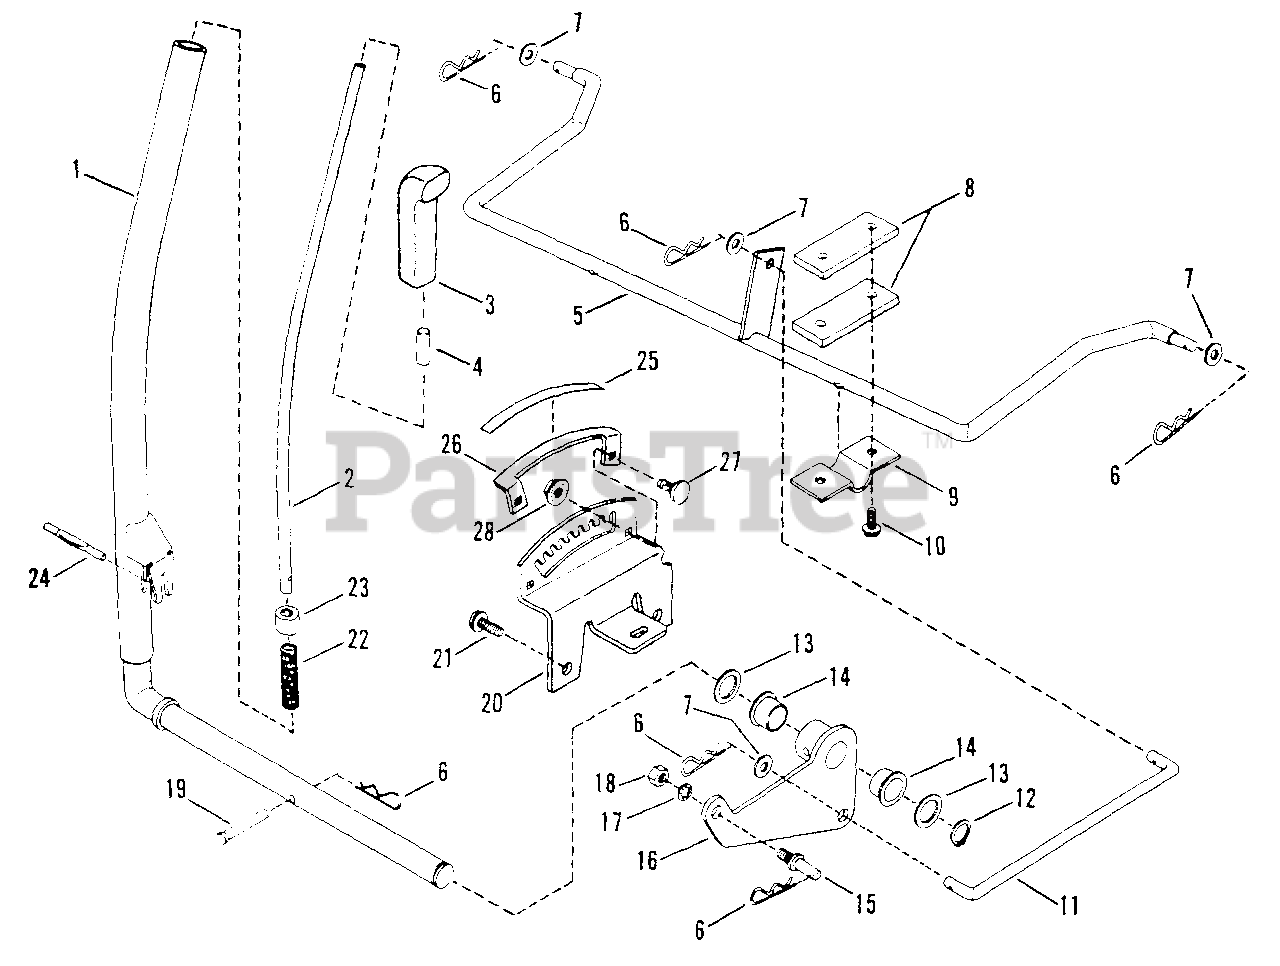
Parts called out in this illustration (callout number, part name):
1	ARM, Implement Lift Lever
2	ROD, Lift Lever
3	GRIP, Lift Lever
4	CAP, Lift Release
5	ARM, Rear Lift
6	PIN, Hair, 3/32x1-1/2"
7	WASHER, 3/8 SAE Flat
9	BRACKET, Arm
10	SCREW, 5/16-18x1 H.W.H.S.T.
11	LIFT-ROD
12	RING, Retaining EXT 7/8"
13	WASHER, Lift Lever .905 x 1.25 x .091
14	BEARING, Lift Lever
15	STUD
16	PIVOT ASSM'Y., Lift Lever
17	WASHER, 3/8 Int. Tooth Lock
18	NUT, 3/8-24 Hex
19	PIN, Clevis, 5/16x1-11/16"
20	QUADRANT, Lift Lever
21	SCREW, 5/16-18x7/8 Self-Tapping
22	SPRING, Lift Lever
23	PLUG, Lift Lever Nylon
24	PIN, 3/16 x 2" Groove
25	DECAL, Cut Height
26	INDICATOR, Cut Height
27	BOLT, 1/4-20x5/8 Flt. Hd. Carr.
28	NUT, 1/4-20 Hex Flg. Lock
